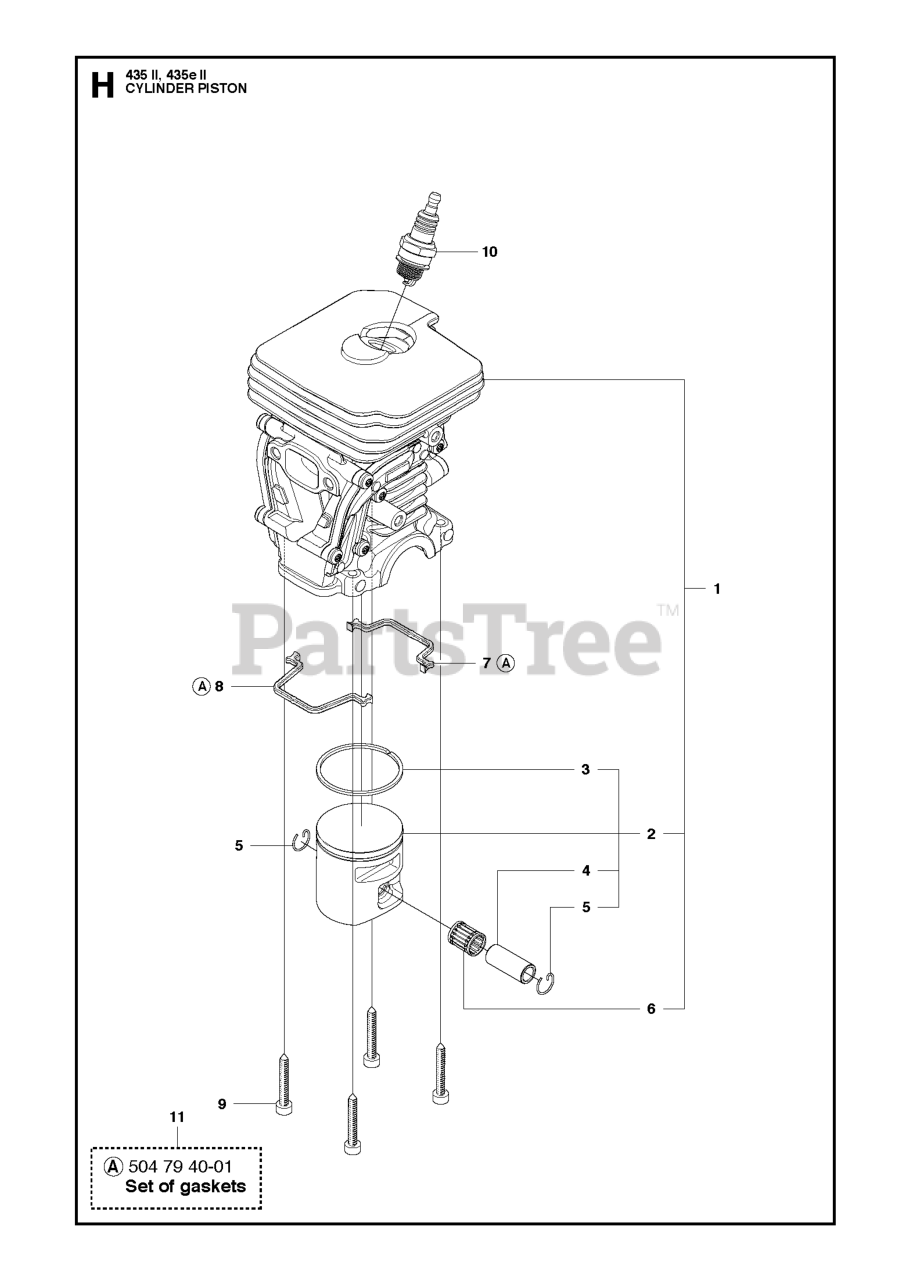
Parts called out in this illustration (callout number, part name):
1	CYLINDER
2	PISTON ASSY
3	PISTON RING
4	PISTON PIN
5	LOCKING RING
6	SUPPORT BUSHING
9	SCREW MC6S 5X25
10	SPARK PLUG M14X1.25 NGK BPMR7A
11	GASKET SET
